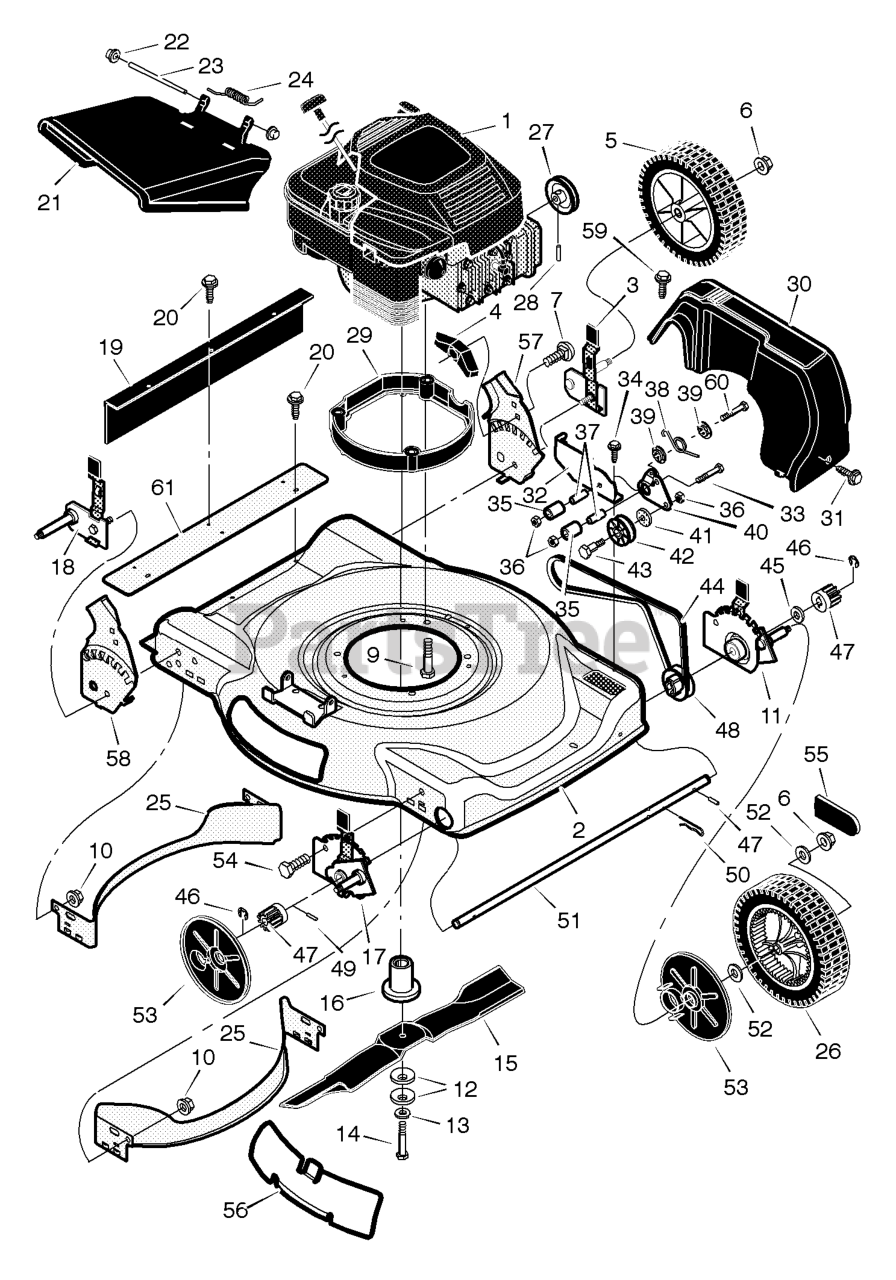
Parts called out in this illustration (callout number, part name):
1	Engine
2	Housing
3	Height Adjuster, Left Rear
5	Wheel and Tire, Rear
6	Locknut, Flange
7	Bolt, Carriage
9	Bolt, Engine
10	Nut
11	Height Adjuster, Left Front
12	Washer, Belleville
14	Bolt, Hex
16	Adapter, Blade
17	Height Adjuster, Right Front
18	Height Adjuster, Right Rear
19	Guard, Rear
21	Deflector, Chute
22	Push-On Cap
23	Pin, Pivot
26	Wheel and Tire, Drive
27	Pulley
28	Pin, Spring
29	Base, Engine
30	Cover, Belt
32	Bracket, Idler Support
35	Idler, Backside
36	Locknut
37	Bearing
39	Spacer
40	Arm, Pivot
41	Spacer
42	Pulley, Idler
43	Bolt, Shoulder
46	Ring, Retainer
47	Gear, Pinion
48	Pulley
49	Pin, Drive
50	Pin, Hair
52	Washer
53	Cover, Dust
54	Bolt
55	Hub Cap
56	Plate, Mulcher
57	Bracket, Left Handle
58	Bracket, Right Handle
61	Extension, Rear
